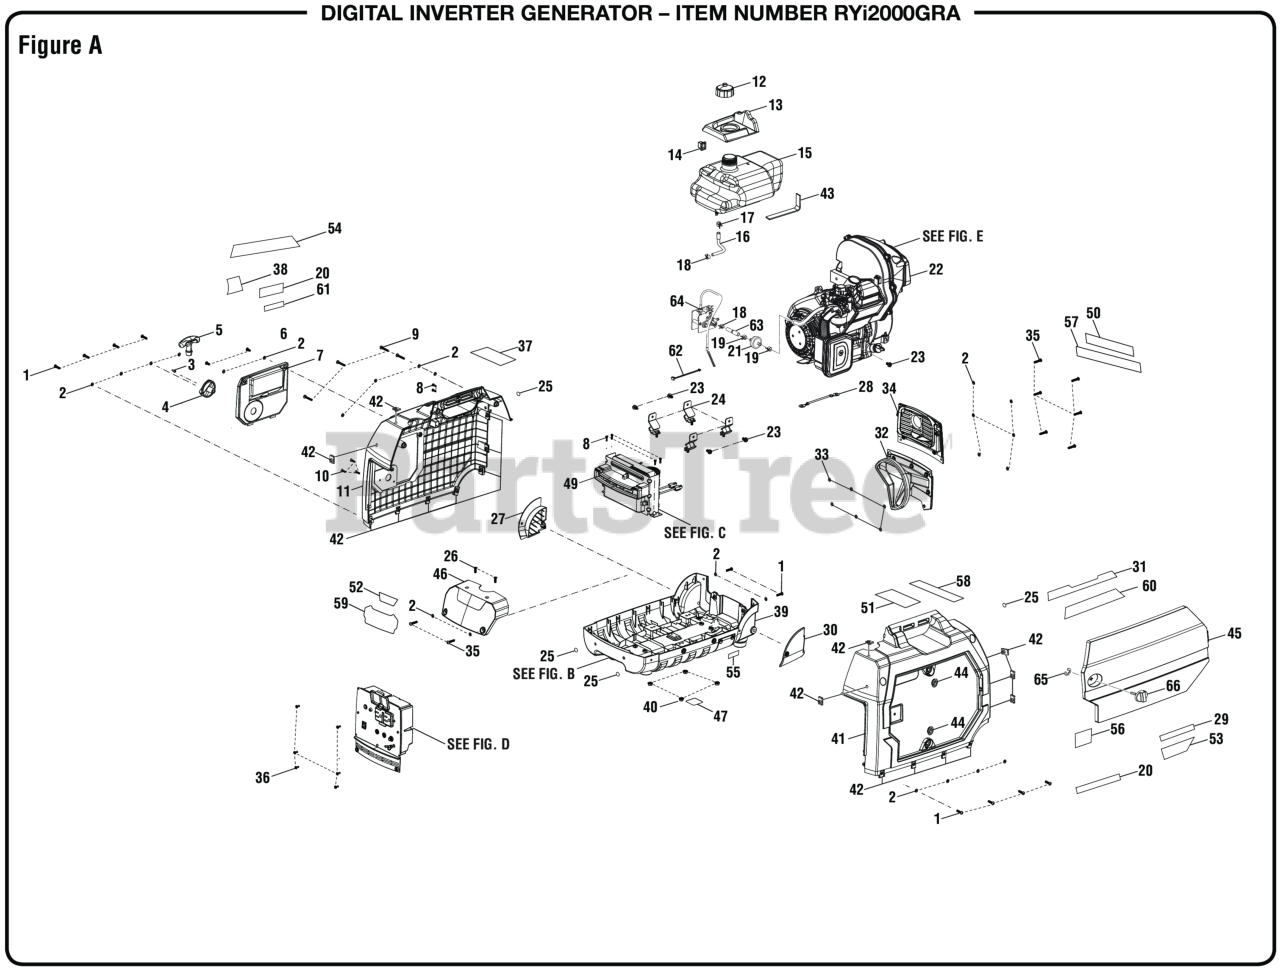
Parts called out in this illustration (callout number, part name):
1	Screw (M5 x 20 mm, Button Soc. Hd.)
2	Washer (ID5.3 x OD10 x 1t)
3	Screw (M4 x 10 mm)
4	Control Knob
5	Recoil Handle
6	Screw (M5 x 12 mm, T25 Torx Pan Hd.)
7	Starter Cover Assembly
8	Screw (M4 x 12 mm, T15 Torx Pan Hd.)
9	Screw (M5 x 30 mm, T25 Torx Pan Hd.)
10	Screw (M4 x 16 mm, Flat Hd.)
11	Left Housing Assembly
12	Vented Fuel Cap
13	Overspill Guard
14	Support (Fuel Tank)
15	Fuel System Assembly
16	Fuel Hose (6mm and 4.5 mm)
17	Clamp (D10 x 0.8 mm)
18	Fuel Line Clamp (3/8 in.)
19	Fuel Hose Clamp (9.5 mm)
20	Easy Start Logo Label
21	Fuel Filter Inline (1/4 in.)
23	Bolt (M6 x 12 mm, Hex Hd.)
24	Engine Isolator (45 Degree)
25	Half Inch Black Round Label
26	Screw (M5 x 16 mm, Flat Hd.)
27	Wheel Cap (Left)
28	Ground Wire
29	Inquires Label (Ryobi)
30	Wheel Cap (Right)
31	Fire Distance Label
32	Lower Exhaust Panel Assembly
33	Internal tooth washer (5 mm ID)
34	Upper Exhaust Panel Assembly
35	Screw (M5 x 25 mm, Button Soc. Hd.)
36	Screw w/Washer (M4 x 10 mm, T20 Torx Button Hd.)
37	Danger Label
38	Choke Label
39	Bottom Base Assembly
40	Lock Nut (M6)
41	Right Housing Assembly
42	U-Clip (M5)
43	Rubber Pad
45	Maintenance Cover Assembly
46	Front Housing Cover
47	Upright Storage Label
48	Control Panel
49	Inverter Module Assembly
50	Combustion Label
51	CPSC Danger Label
52	Start Label (Hood)
53	Lubricant Label
54	Performance Label
55	Internally Placed Maintance Label
56	Fuel Stabilizer Label
57	Ground Warning Label (English/French)
58	Exhaust Direction Label
59	Logo Label
60	Performance Label (Maintenance Door)
61	Start Label
62	Engine Wire Harnes
63	Fuel Hose (4.5 mm and 6 mm)
64	Engine Start/Stop Mechanism Assembly
65	E-Clip (5 mm Shaft)
66	Lock Knob
